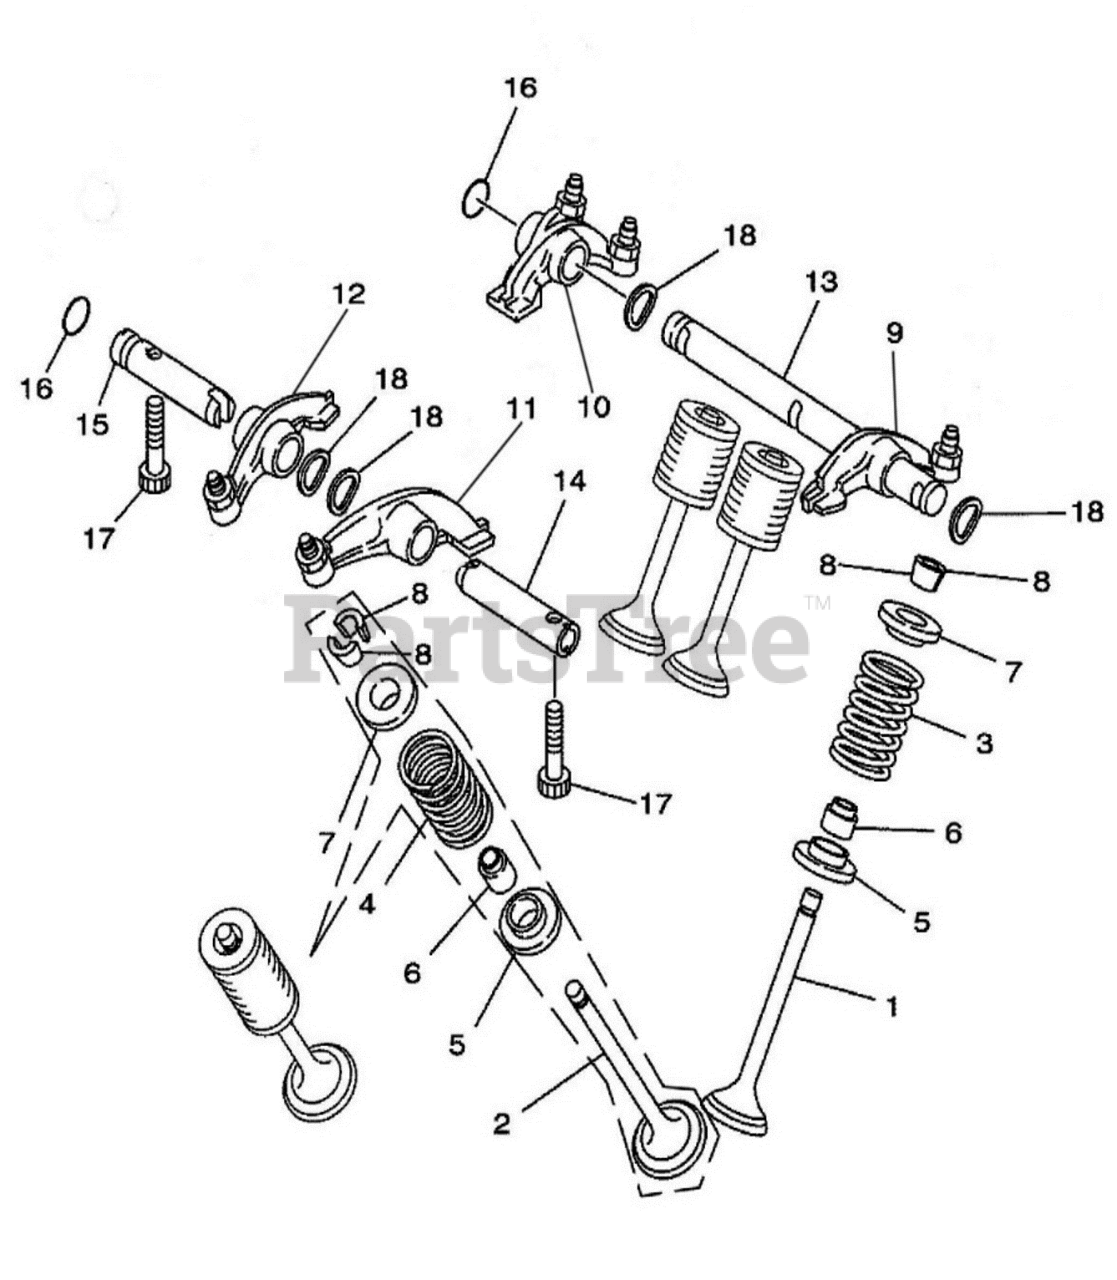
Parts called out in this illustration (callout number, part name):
1	INTAKE VALVE
2	EXHAUST VALVE
3	INTAKE VALVE SPRING
4	EXHAUST VALVE SPRING
5	VALVE SPRING WASHER
6	VALVE STEM SEAL
7	VALVE SPRING RETAINER
8	VALVE LOCK CLAMP
9	INTAKE VALVE ROCKER
10	INTAKE VALVE ROCKER ARM
11	EXHAUST VALVE ROCKER II
12	EXHAUST VALVE ROCKER I
13	INTAKE VALVE ROCKERSHAFT
14	EXHAUST VALVE ROCKERSHAFT I
15	EXHAUST VALVE ROCKERSHAFT II
16	O-RING 9X2
17	HEX HEAD CAP SCREWM6X20
18	WAVE MODE WASHER 12.5X34X0.4
